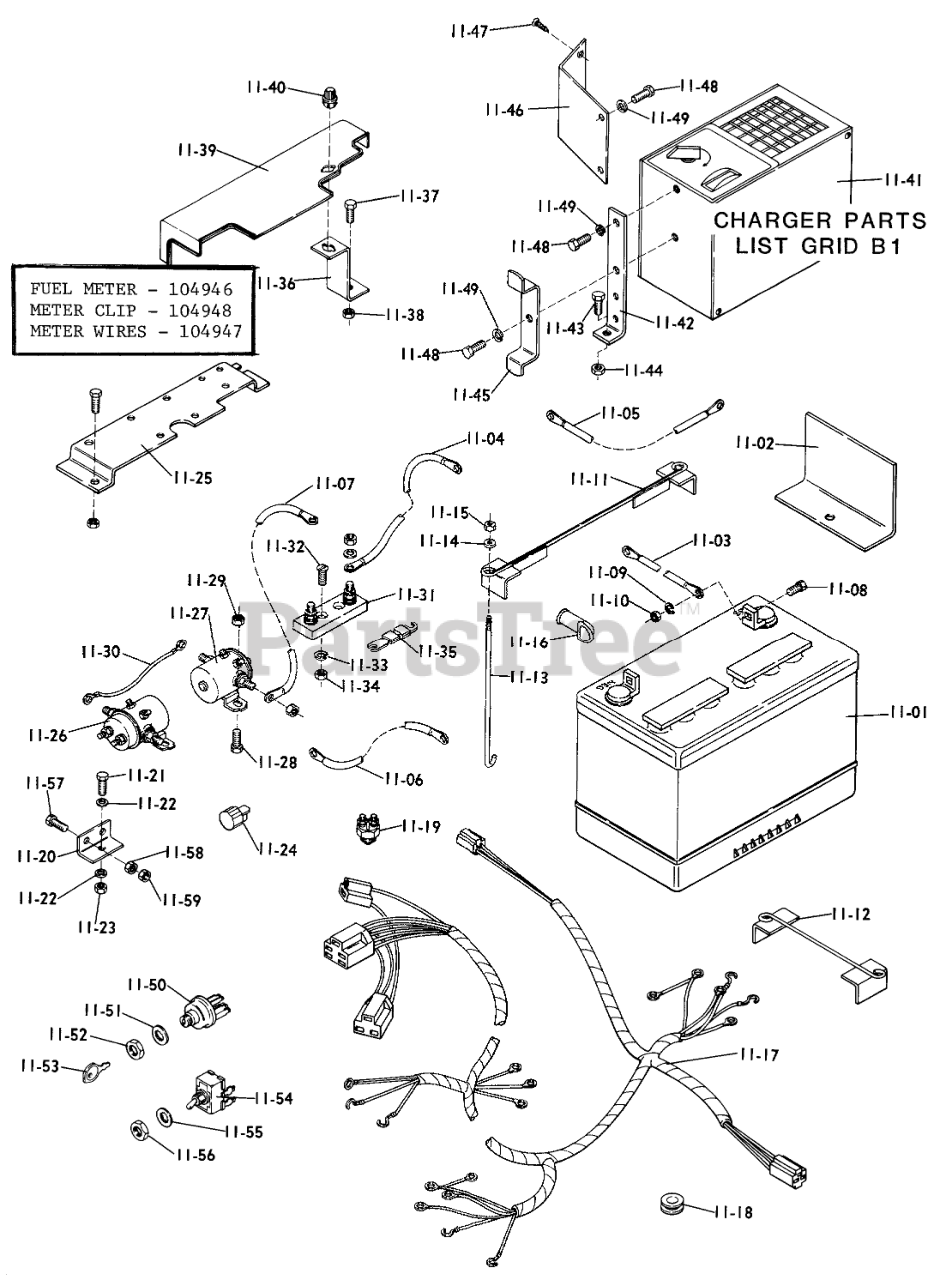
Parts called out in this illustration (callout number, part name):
11-01	Battery
11-02	Battery Shield
11-03	Battery Cable, Short
11-04	Battery Cable, Positive
11-05	Battery Cable, Negative
11-06	Cable-Solenoid To Batt. Pos
11-07	Cable, Solenoid to Fuse
11-08	Bolt
11-09	Lockwasher
11-10	Nut
11-11	Hold Down Assembly
11-12	Assy-Hold Down
11-15	Nut
11-16	Terminal Cover
11-17	Wiring Harness
11-18	GROMMET
11-19	SWITCH SAFETY
11-20	Ground Bar
11-21	Bolt
11-22	WASHER 5/16 NYLON
11-23	Nut
11-24	Diode
11-25	Mounting Plate
11-26	SOLENOID-MOWER MOTOR
11-27	Solenoid-Traction Motor
11-28	Bolt
11-29	Nut
11-30	Solenoid Wire
11-31	Fuse Block
11-32	Screw, Flat Head Machine #10-24 x 3/4
11-33	Lockwasher
11-34	Hex Nut
11-36	Cover Strap
11-37	Bolt
11-38	Nut
11-39	Wiring Cover
11-40	Release Button
11-41	Charger
11-42	Support Strap
11-43	Bolt
11-44	Nut
11-45	Cord Bracket
11-46	Charger Bracket
11-47	Screw, Flat Hd. 1/4-20 x 3/4 Swage Form
11-48	H H C S
11-49	Lockwasher
11-50	SWITCH-IGNITION
11-51	Lockwasher 9/16 I.D.
11-52	Nut
11-53	Key-EL
11-54	PTO Switch
11-55	Lockwasher 1/2 Int. Tooth
11-56	Nut, 1/2-27
11-57	Bolt
11-58	Nut
11-59	Nut
